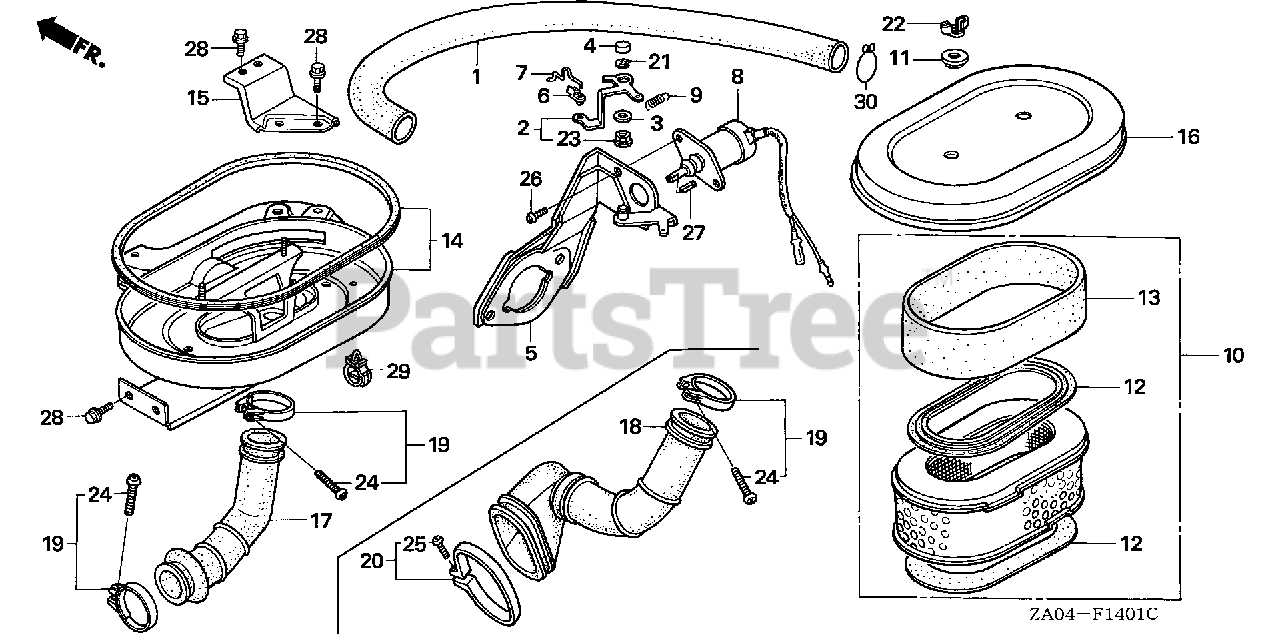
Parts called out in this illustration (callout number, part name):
1	TUBE, BREATHER
2	LEVER, SOLENOID CHOKE
3	SEAL, CHOKE LEVER
4	CAP, CHOKE LEVER
5	STAY, SOLENOID
6	JOINT, ROD
7	ROD, CHOKE SOLENOID
8	SOLENOID, CHOKE
9	SPRING, CHOKE RETURN
10	ELEMENT, CLEANER
11	WASHER, AIR CLEANER COVER
13	FILTER (OUTER)
14	HOUSING, AIR CLEANER
15	STAY B, AIR CLEANER
16	COVER, AIR CLEANER *NH116M* (URBAN SILVER METALLIC)
18	TUBE, AIR CLEANER
19	BAND, CONNECTING TUBE
20	BAND, CONNECTING TUBE
21	E-RING (4MM)
22	WINGNUT, AIR CLEANER COVER
23	BUSH, CHOKE LEVER
24	SCREW, PAN (4X26)
25	SCREW, PAN (4X20)
26	SCREW, PAN (5X8)
27	PIN, SPRING (2.5X16)
28	BOLT, FLANGE (6X10)
29	STRAP, WIRE HARNESS (25MM) (BLACK)
30	CLIP, BREATHER TUBE
